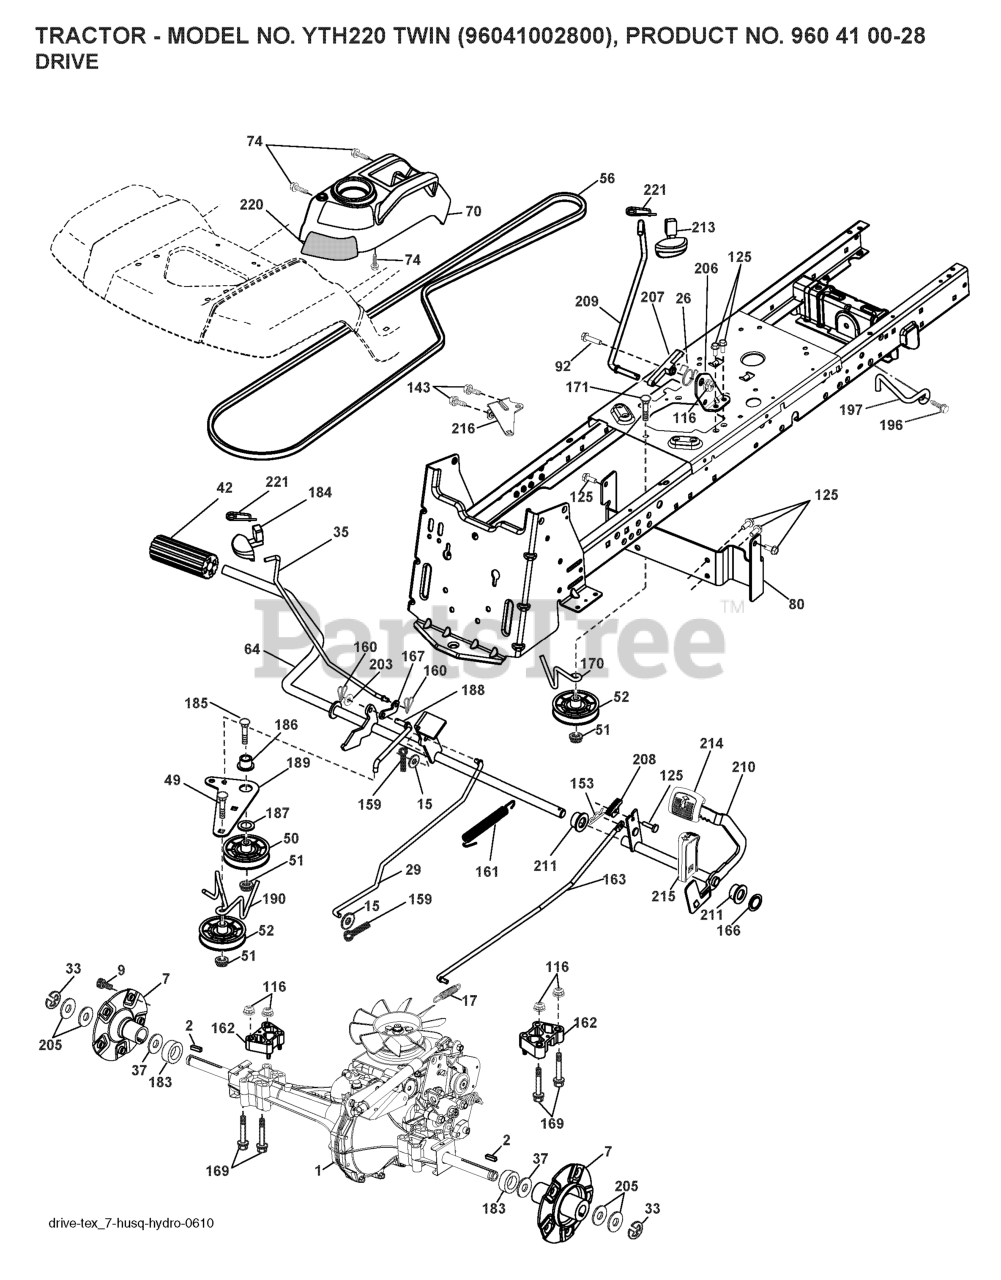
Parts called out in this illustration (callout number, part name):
2	KEY.SQUARE.187X2.500
7	HUB.ASM.WHEEL.REAR.22"
9	HUB BOLT
15	WASHER
17	SPRING.BRAKE.HG3000/3500
26	SPRING.RETURN.CRUISE
29	ROD.BRAKE.0610.PEDAL.CONTROL
35	ROD.BRAKE.PARKING.GT.H
42	PEDAL COVER T
50	IDLER.FLAT.910.OFFSET
51	NUT LOCK FLG 3/8-16 UNC
52	IDLER.V-GROOVE.910.OFFSET
64	SHAFT.ASM.PEDAL.BRK.CNTR
70	RP CONSOLE.ASM.PCH.W/TB
74	SCREW.HI-LO.CONSOLE
80	BRKT.STRP.TRQ.LT.HYD.C
92	BOLT
116	NUT LOCK HEX FLANGE 5/16-18
125	SCREW
143	Screw 5/16-18 x 1/2 Hex, Self Tapping 5/16-18 x 1/2
153	RETAINER M
159	COTTER PIN
160	RETAINER CLIP
161	SPRING.RETURN.CLUTCH.2006
162	SPACER.TRANSAXLE.18&22
163	ROD.PEDAL.CONTROL.0510
166	NUT.PUSH.625.2006
167	LATCH.BRAKE.SPRING
169	BOLT.HEX.FLNG.5/16-18X3.75
170	KEEPER.V-IDLER.CENTER.
171	BOLT
183	SPACER.SPLIT.800X.350
184	HANDLE.PARKG.BRK.HUSQ X667
185	BOLT
186	SPACER.RETAINER
187	WASHER 12/32X2X10GA
188	RP.LINK.CLUTCH.GROUND.DRIVE
189	BELLCRANK.GROUND.DRIVE.TEX.
190	KEEPER.BELLCRANK.DRIVE
196	SCREW 3/8-16X1
197	BRKT.ANIT-ROTATION.CLUTCH
203	WASHER
206	BRKT.MOUNT.LATCH.CRUIS
207	LATCH.CONTROL.CRUISE
208	GEAR.SECTOR.CONTROL.CR
209	ROD.CONTROL.CRUISE.GT.
210	ROCKER.ASM.PEDAL.CONTR
211	BEARING.NYLON
213	KNOB.CONTROL.CRUSIE.HU
214	PEDAL.FORWARD.TEX.GT.4
215	PEDAL.REVERSE.TEX.GT.4
216	BRACKET.PULLEY.IDLER.W/TEX
220	REFLECTOR.RH.TEX GT
221	RETAINER.SPRING.CLIP.H
222	WASHER
